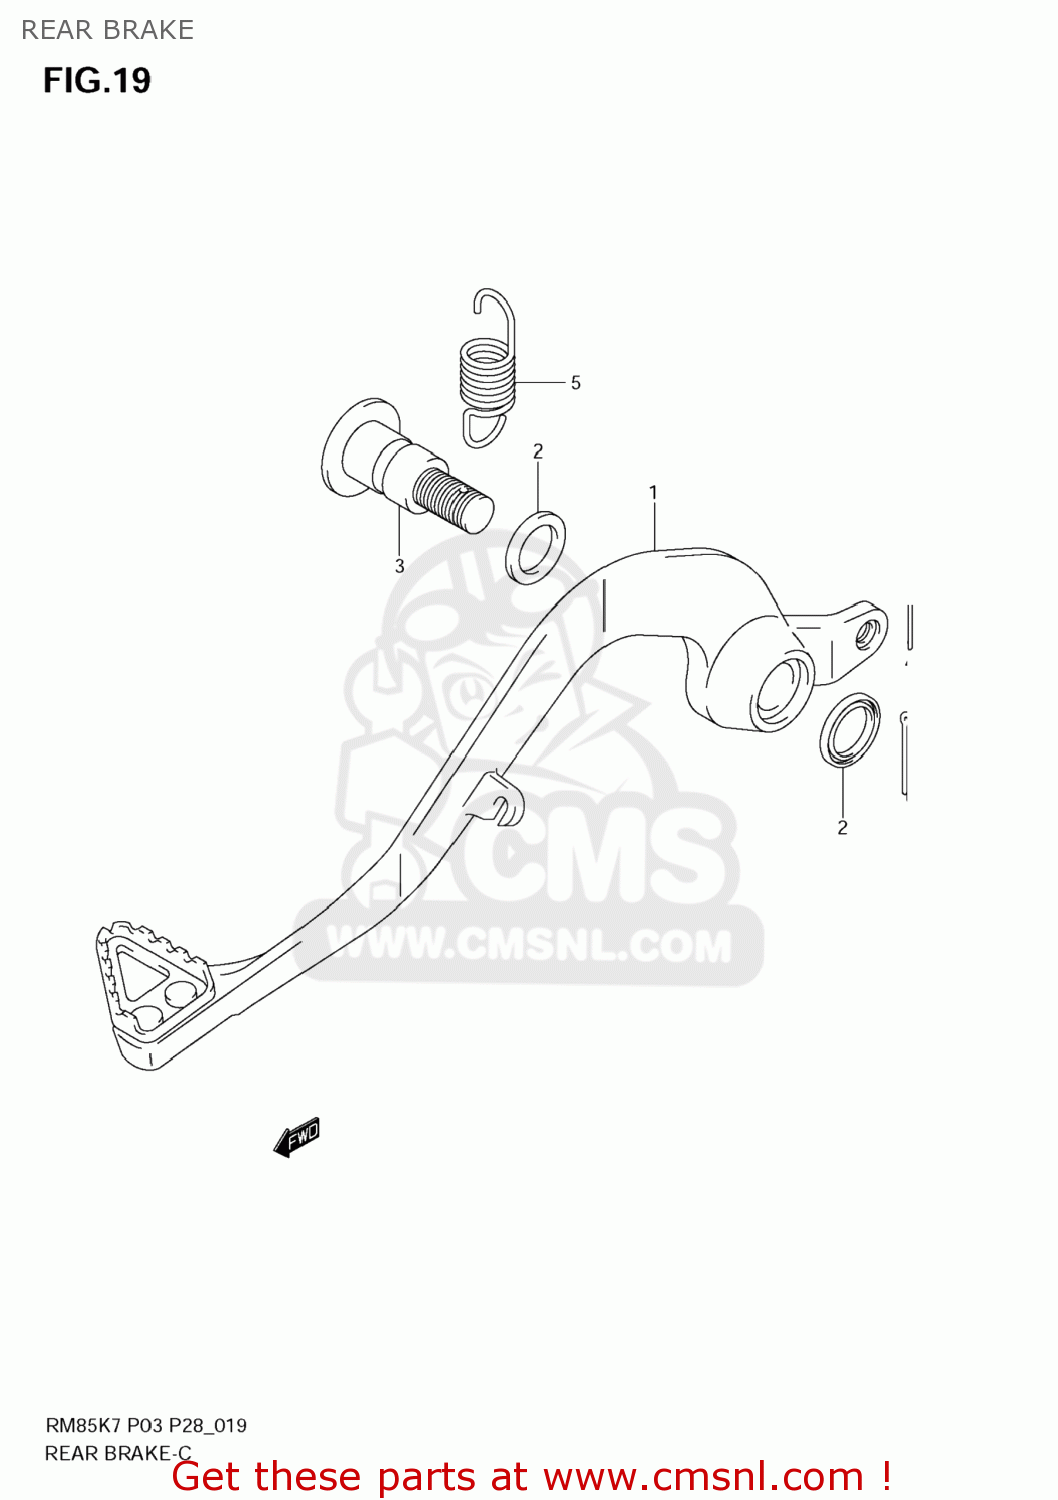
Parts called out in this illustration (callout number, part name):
1	PEDAL ASSY,BRAKE
2	SEAL,OIL(15X21X3)
3	SHAFT,BRAKE PEDAL
4	PIN
5	SPRING
